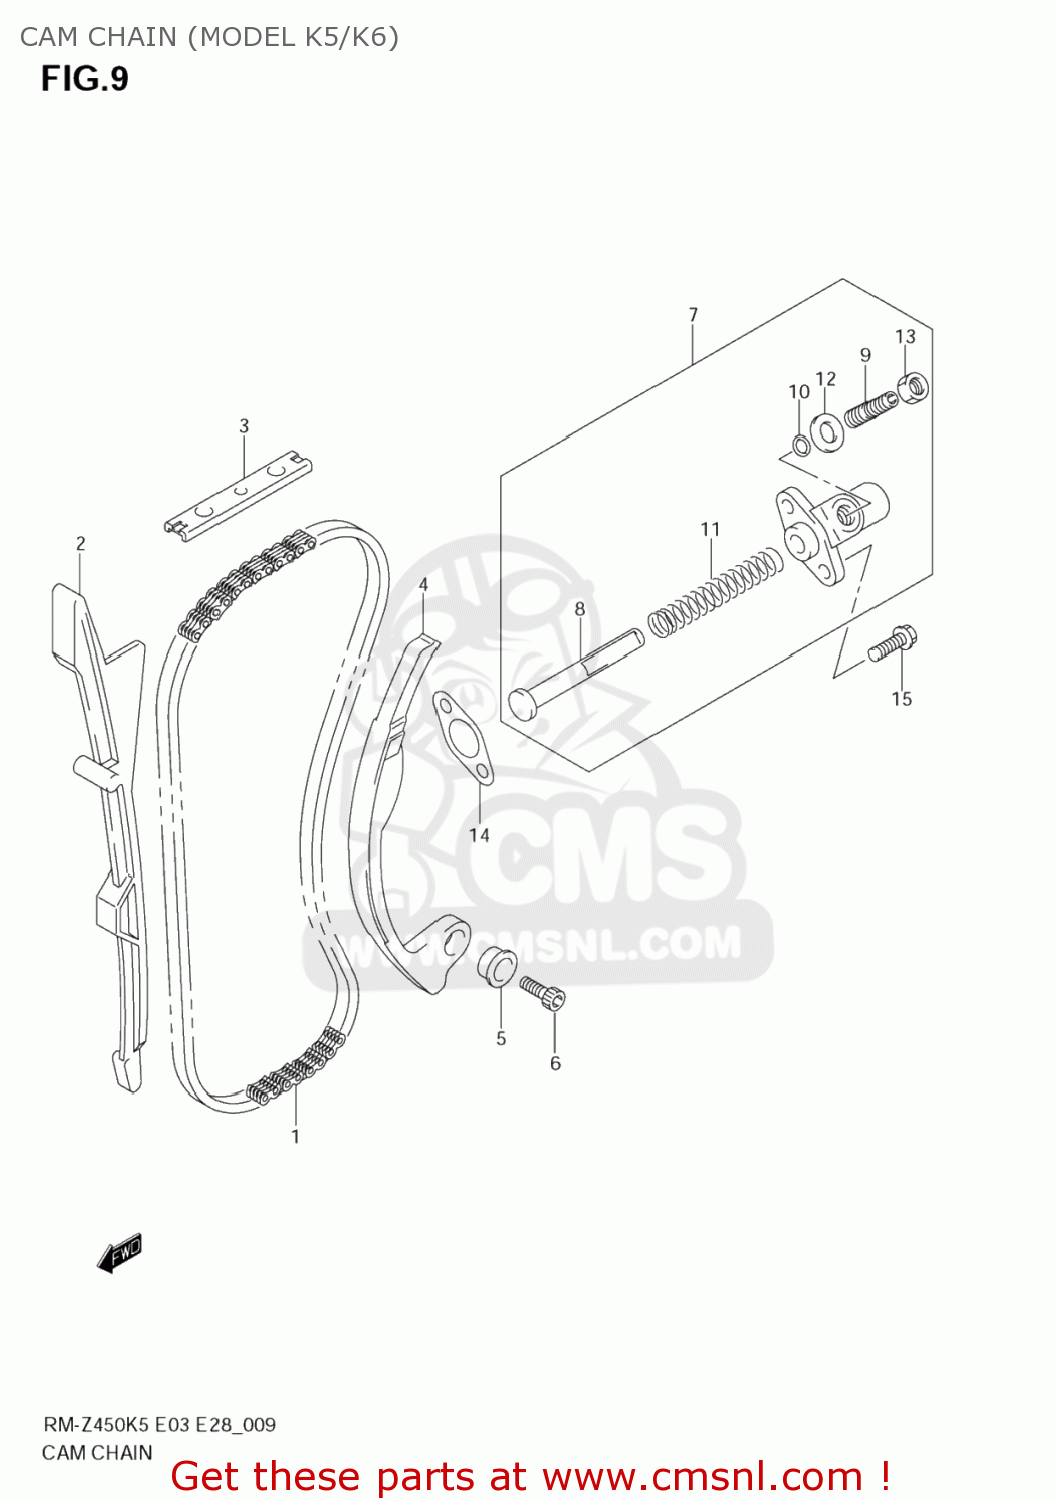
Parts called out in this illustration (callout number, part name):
1	CHAIN COMP,CAM
2	GUIDE,CAM CHAIN NO.1
3	GUIDE,CAM CHAIN NO.2
4	TENSIONER,CAM CHAIN
5	SPACER,CAM CHAIN TENSIONER
6	BOLT,OIL FILLE
7	ADJUSTER ASSY,TENSIONER
8	ROD,PUSH
9	BOLT,ADJUST
10	O RING(D:1.9,ID:5.7)
11	SPRING
12	WASHER
13	NUT
14	GASKET,TENSIONER ADJUSTER (NAS)
15	BOLT,6X20
